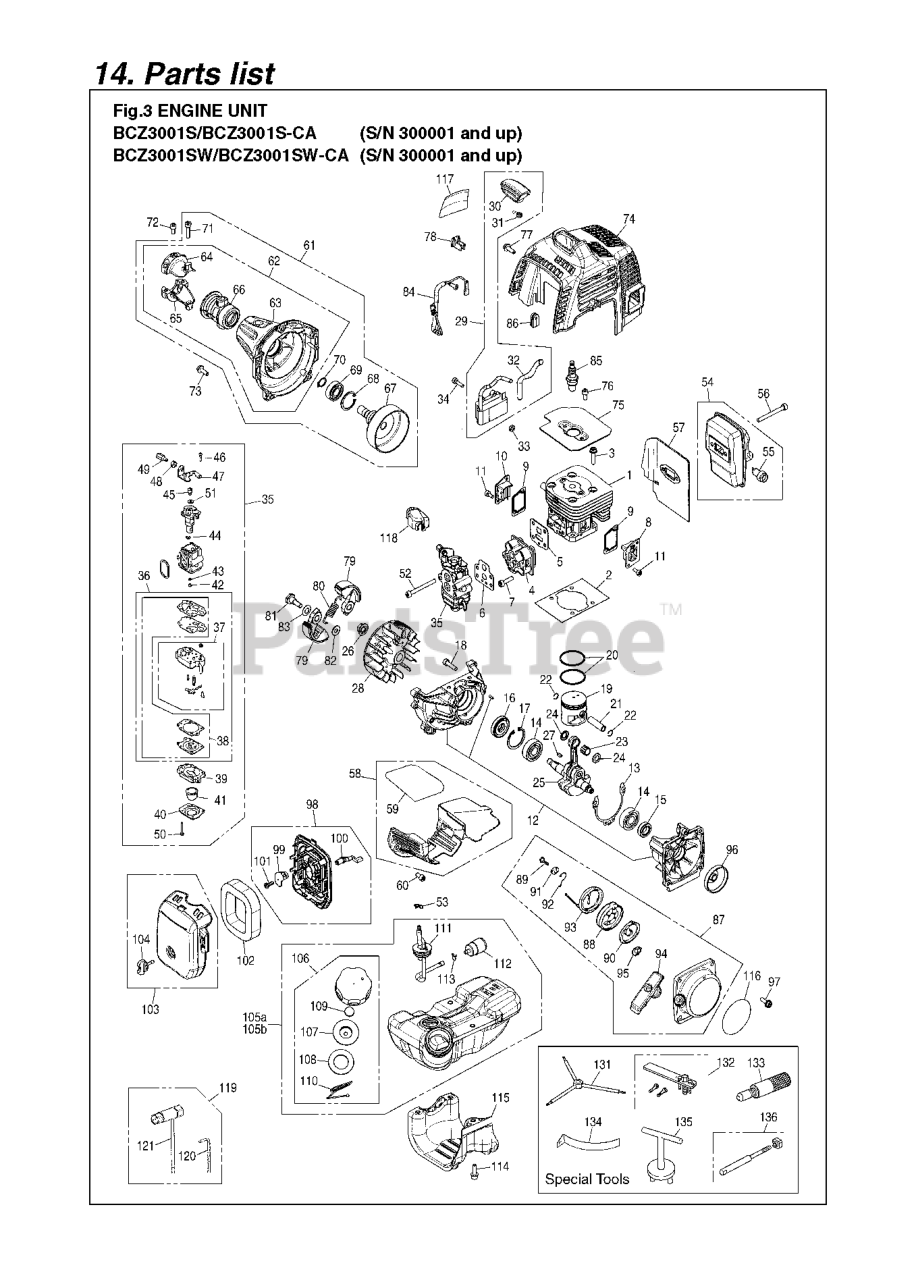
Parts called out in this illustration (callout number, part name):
1	CYLINDER (RPLS 848F6012A1&A2)
2	GASKET BASE
3	BOLT
4	INSULATOR
5	GASKET.INSU
6	GASKET, CARB (RPLS T155113131)
7	BOLT, TORX
8	COVER, TRS
9	GASKET, TR
10	COVER,TRF (RPLS 848F6012D1)
11	BOLT
12	CRANKCASE-C
13	GASKET CASE
14	BEARING
19	PISTON (RPLS 848F6041A1)
20	RING
21	PIN
25	CRANKSHAFT-C
26	NUT
27	KEY
29	COIL-A
30	CAP
31	SPRING
33	SPACER
35	CARBURETOR (RPLS 848-F60-8101)
36	REBUILD KIT
37	CARBURETOR BODY
38	GASKET KIT
40	1OVER
41	PUMP
44	RING
45	SWIVEL
46	SCREW
47	BRACKET
48	NUT
49	ADJUSTER
51	WASHER
53	CLIP
54	MUFFLER
55	ARRESTER
57	GASKET
58	PLATE-A
61	HOUSING ASSY
62	HOUSING COMP.
64	BRACKET (A) (RPLS T170031211)
65	BRACKET (B)
67	DRUM (RPLS 481031120-22)
69	BEARING
74	COVER.ENGINE
75	RP_PLATE
83	WASHER
84	CORD-COMP
85	PLUG CMR7H
87	RECOIL ASSY
90	SPRING, SPIRAL
91	COLLAR
92	SWING ARM
95	PLATE.STOPPER
98	BODY ASSY
99	PLATE.CHOKE
100	LEVER CHOKE
101	SCREW
103	COVER-A (RPLS T155182200)
107	HOLDER-A
111	PIPE-C
112	FILTER ASSY
113	CLIP
115	GUARD, TANK
119	TOOL SET (RPLS 848-8UD-0120)
121	SOCKET
131	WRENCH
132	FLYWHEEL PULLER
133	STOPPER
134	GAUGE
135	PULLER
136	ROD-A
